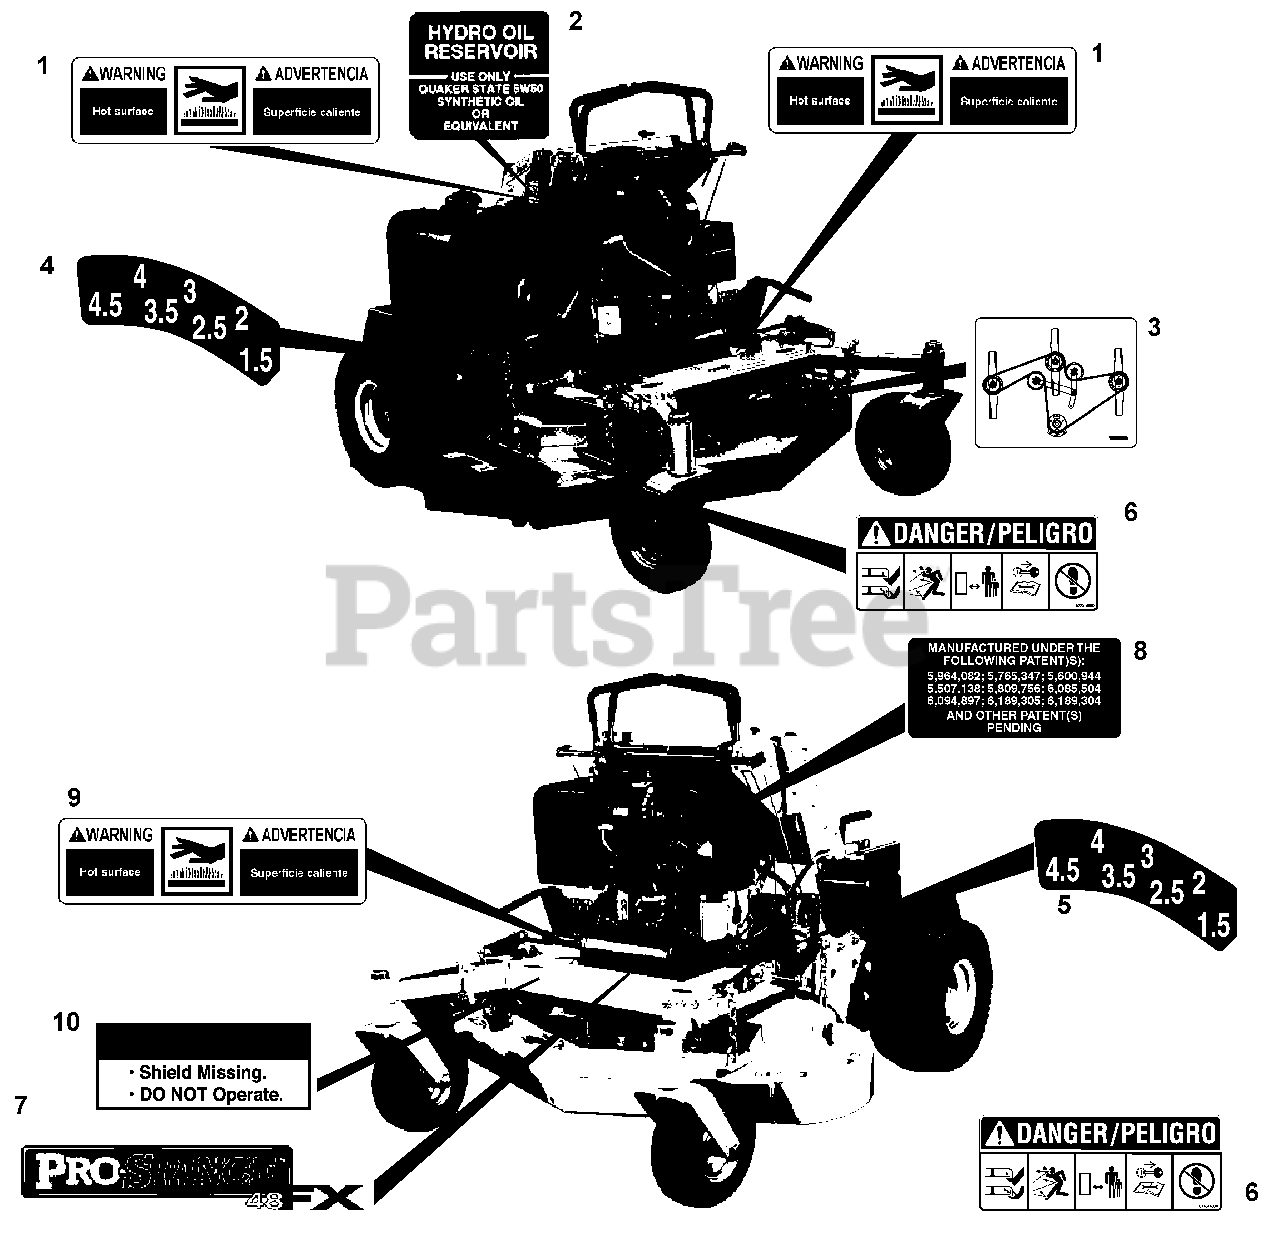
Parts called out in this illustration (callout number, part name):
1	Decal, Warning, Hot Surface (994100)
2	Decal, Hydro Oil Specs
3	Decal, Belt Path
4	Decal, Cut Height RH
5	Decal, Cut Height, LH
6	Decal, Mower Fan Danger
7	Decal, Pro-Stance 1948FX (994100)
8	Decal, Patent
9	Decal, Warning
10	Decal, Warning, Shield
